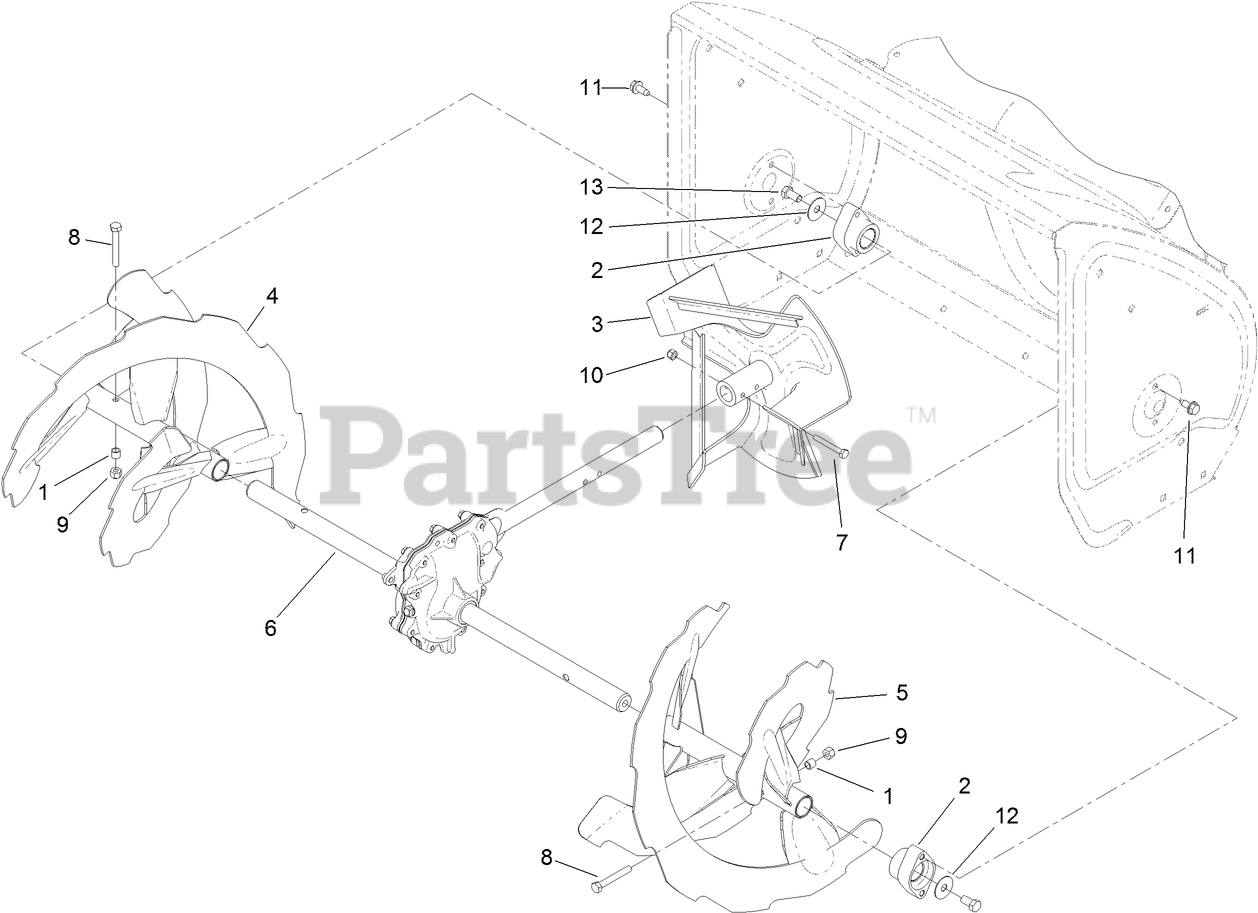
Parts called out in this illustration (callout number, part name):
1	SPACER-GROMMET
2	BEARING-AUGER
3	IMPELLER ASM
4	RH AUGER ASM
5	LH AUGER ASM
6	28 INCH AUGER GEARCASE ASM
7	SCREW-HH
8	SCREW-HH
9	NUT-HEX
10	NUT-HEX
11	SCREW-HWHTF
12	WASHER
13	SCREW-HH
